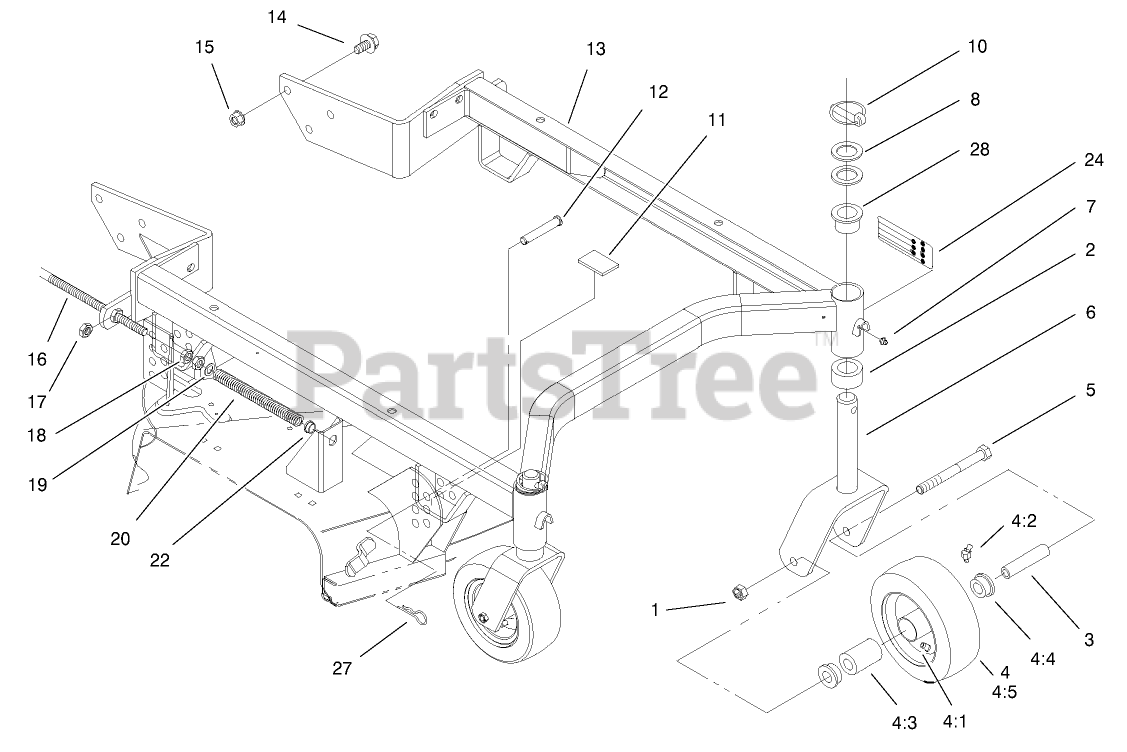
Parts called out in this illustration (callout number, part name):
1	NUT-HEX
2	SPACER-CASTOR
3	BUSHING-SPANNER
4	CASTER WHEEL ASM
4:1	STEM-VALVE
4:2	FITTING-LUBE, 45 DEG
4:3	BEARING
4:4	BEARING-OUTSIDE
4:5	TIRE-TUBELESS
5	SCREW-HH
6	CASTOR FORK ASM
7	FITTING-GREASE
8	WASHER-THRUST
10	PIN-LYNCH
11	CUSHION-RUBBER
12	PIN-CLEVIS
13	44IN CARRIER FRAME ASM
14	SCREW-HHF
15	NUT-HF
16	SHAFT-ADJUSTING
17	NUT-LOCK, NI
18	NUT-JAM
19	WASHER
20	SPRING
22	BUSHING-FLANGE
24	DECAL-HOC
27	PIN-HAIR
28	BUSHING
